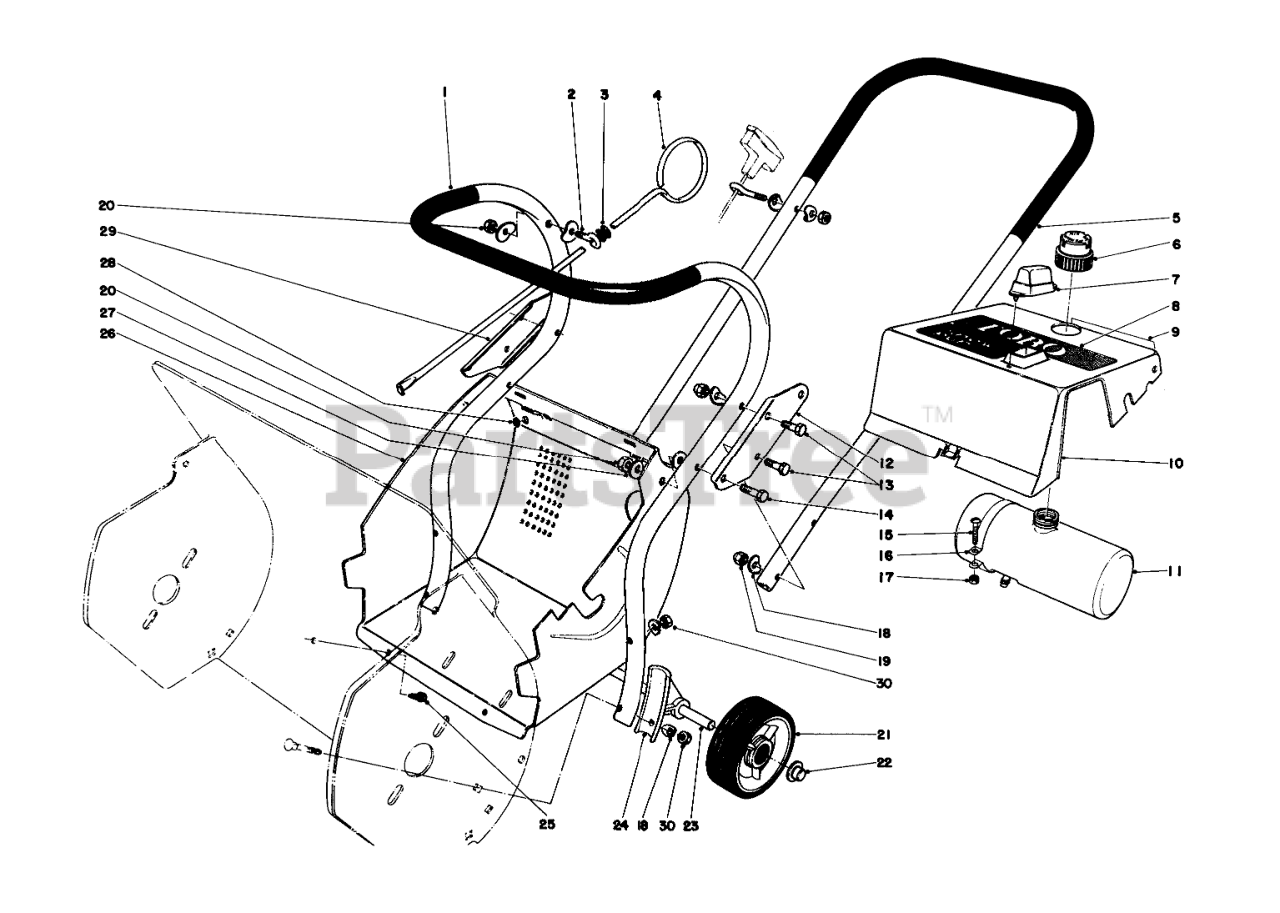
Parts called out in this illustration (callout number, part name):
1	Lower Handle
2	Bolt-Eye
3	GROMMET
4	Vane Adj. Rod
5	Upper Handle
6	Cap, Gas
8	Decal
9	Decal
10	Shroud, Upper (Incl. Ref. No. 7, 8 & 9)
11	Gas Tank Assembly (Incl. Ref. No. 6)
12	SPLICE PLATE
13	SCREW-HH
14	SCREW-HH
15	10-24 X 1 RND HD MS
16	1/2 GAS TANK CLAMP
17	NUT-SQ
18	WASHER
19	NUT-CAP
20	NUT-LOCK
21	Wheel
22	RETAINER-PUSH ON
24	Wheel Bracket
25	SCREW-HWHTF
26	Lower Shroud (Incl. Ref. No. 28)
27	WASHER-FLAT
28	SNO PUP PLATED EYELET
29	Plate-Splice
30	NUT-HEX
